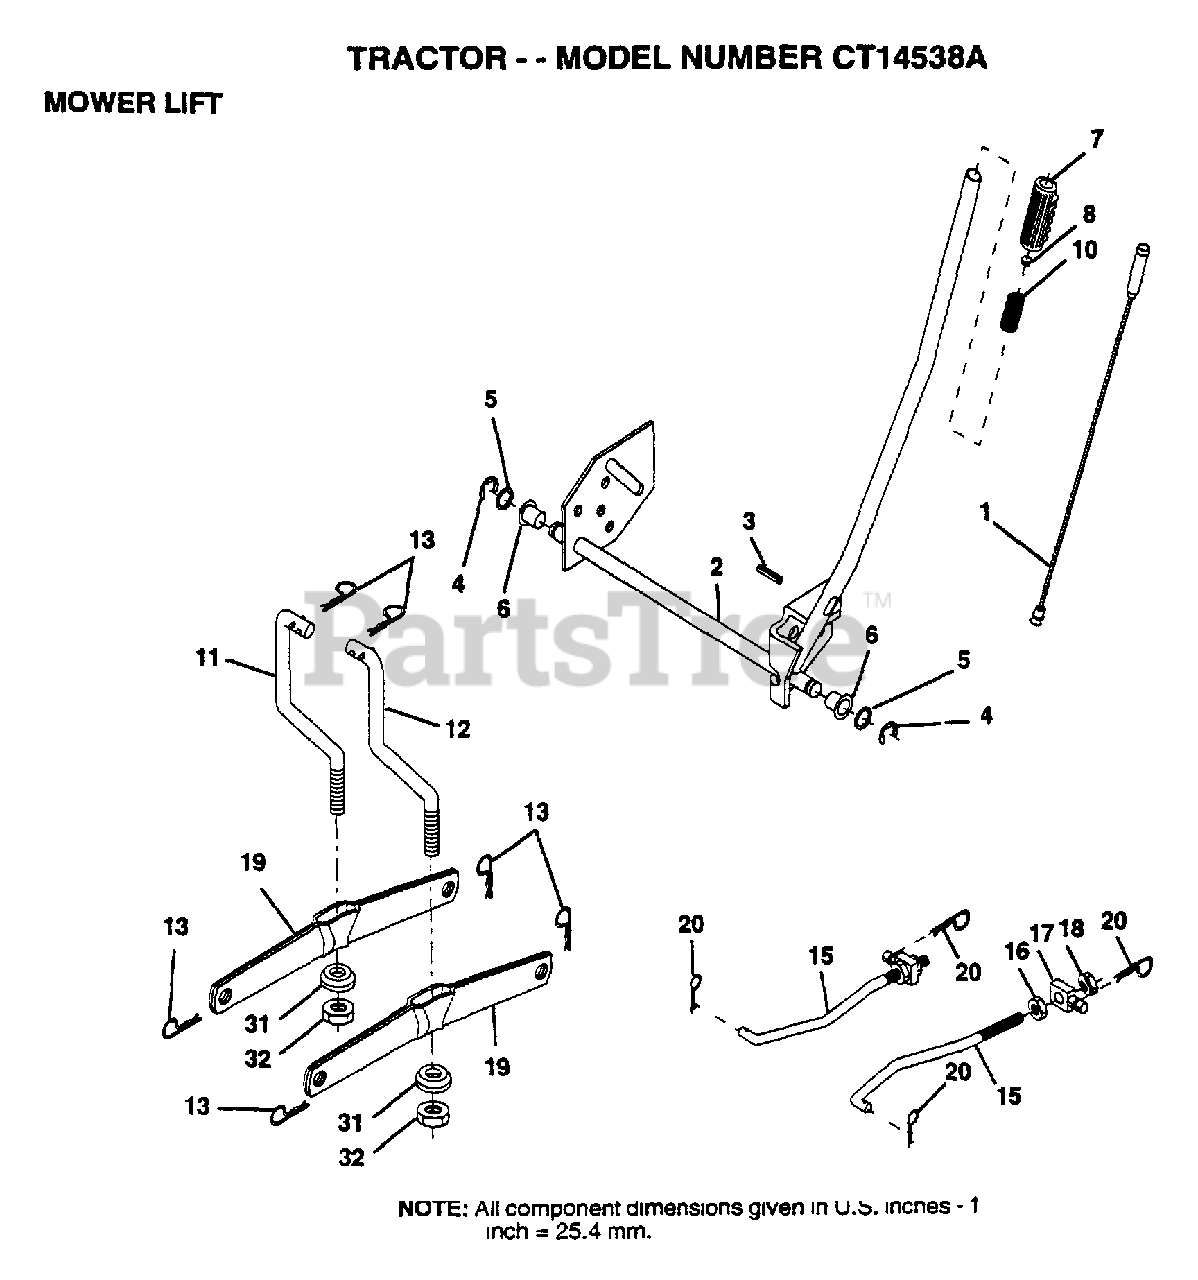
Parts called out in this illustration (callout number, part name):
1	WIRE ASM
3	PIN-GROOVE LT
5	WASHER
6	NYLON BEARING
7	GRIP
15	LINK.FRONT
16	NUT
17	TRUNION
18	NUT.LK.W/WSH.1/2.
19	ARM SUSP REAR
20	RETAINER.SPRING
31	BEARING PVT LH
32	NUT.CROWNLOCK.3/8
